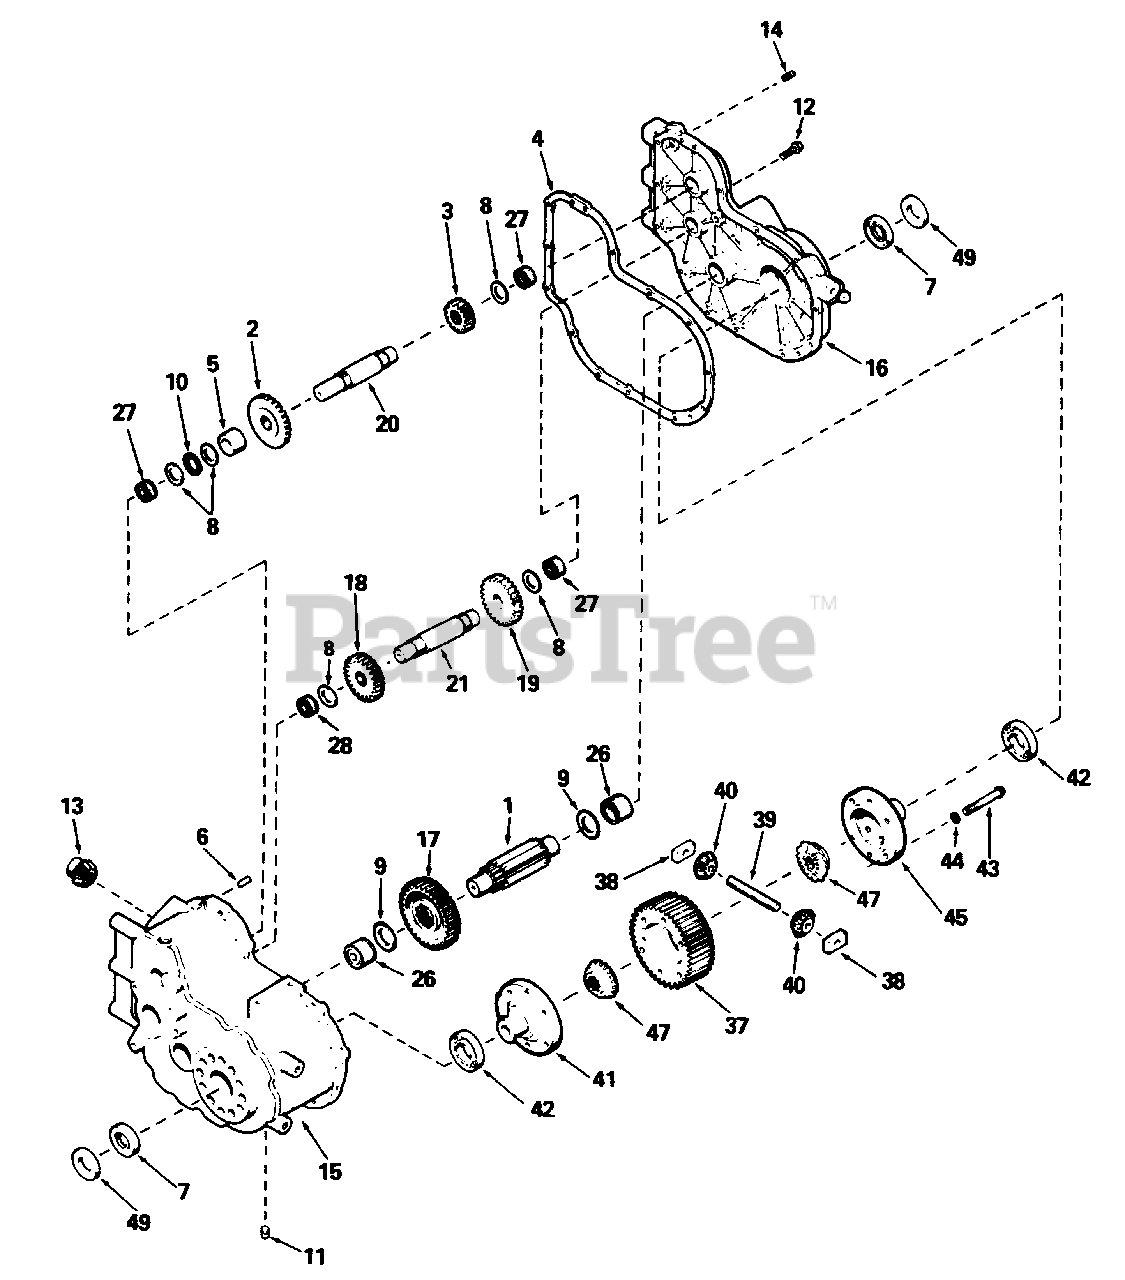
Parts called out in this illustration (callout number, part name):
1	PINION, Output
2	GEAR, Bevel (30 teeth)
3	GEAR, Spur (16 teeth)
4	GASKET, Case & Cover
5	SPACER, 1-5/8 OD x 1-1/64 ID x 55/64 thick
6	PIN, Dowel
7	SEAL, Oil
8	WASHER, Thrust, 1.542 OD x 1.007 ID x .060 thick
9	WASHER, Thrust, 1.917 OD x 1.257 ID x .060 thick
10	BEARING, Thrust
11	PLUG, Magnetic drain, 3/8-18
12	SCREW, Hex Hd. Threadforming, 5/16-18 x 1
13	PINION, Bevel
14	PLUG, Pipe, 1/8-27
15	CASE ASSY., Transaxle (Incl. Ref. Nos. 26, 27 & 28)
16	COVER ASSY., Transaxle (Incl. Ref. Nos. 26 & 27)
17	GEAR, Output (33 teeth)
18	GEAR, Spur (17 teeth)
19	GEAR, Spur (27 teeth)
20	SHAFT, Counter
21	SHAFT, Brake
26	BEARING, Needle
27	BEARING, Needle
28	BEARING, Needle
37	GEAR, Ring
38	BLOCK, Drive
39	PIN, Drive
40	PINION, Bevel
41	CARRIER, Differential
42	BEARING, Ball
43	SCREW, Hex Flanged Hd., 3/8-16 x 2-3/4
44	LOCKWASHER, 3/8"
45	CARRIER, Differential
47	GEAR, Bevel
49	SPACER, 2-1/8 OD x 1-5/32 ID x 3/8 thick
